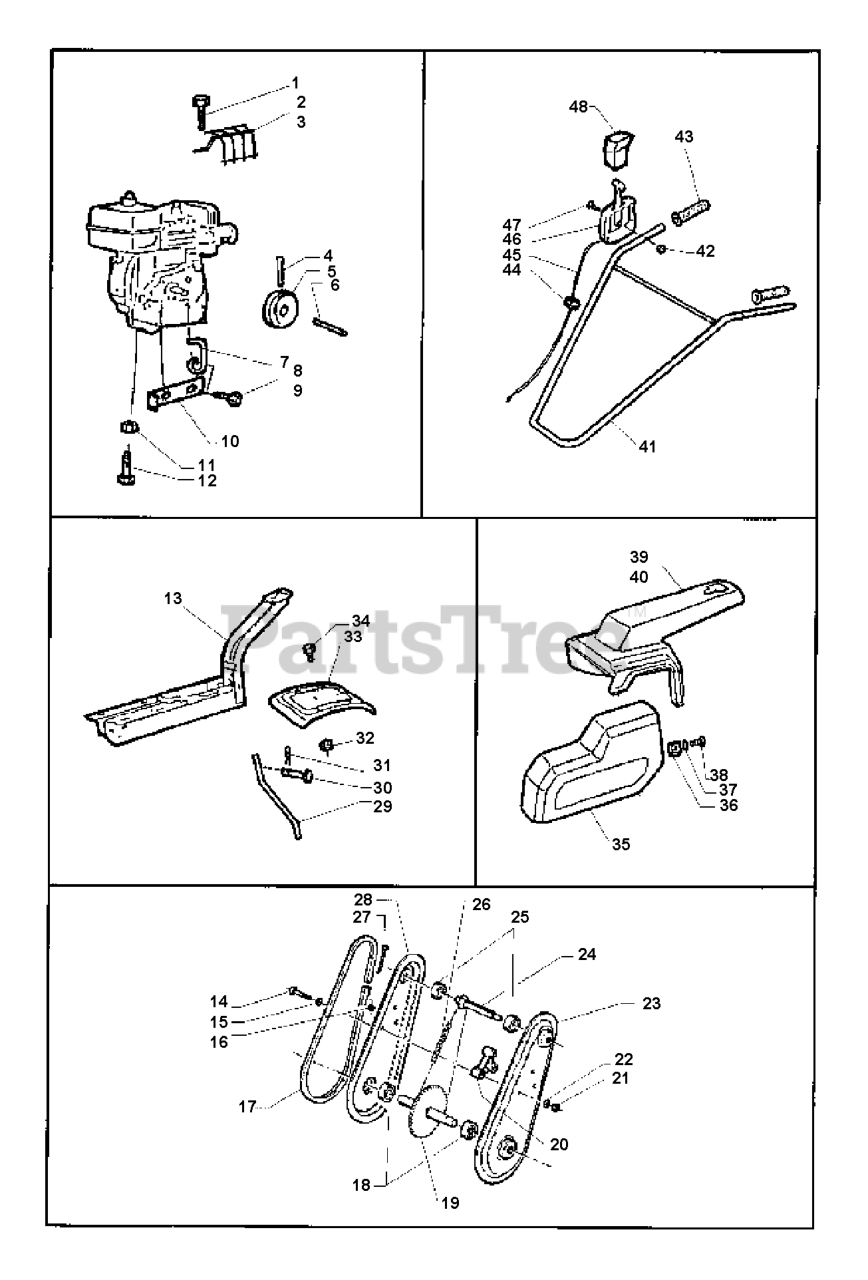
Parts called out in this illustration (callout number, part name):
1	SCREW
2	PROTECTOR
3	GRATE
7	BELT GUIDE
9	SCREW
15	WASHER - 15X7.3X1.6
16	Blocking nut M 6 Z
22	WASHER - 15X7.3X1.6
26	DRIVE CHAIN
31	COTTER PIN
36	NUT
39	COVER
40	COVER
46	THROTTLE CONTROL
48	REPL BY 516 83 63-15
